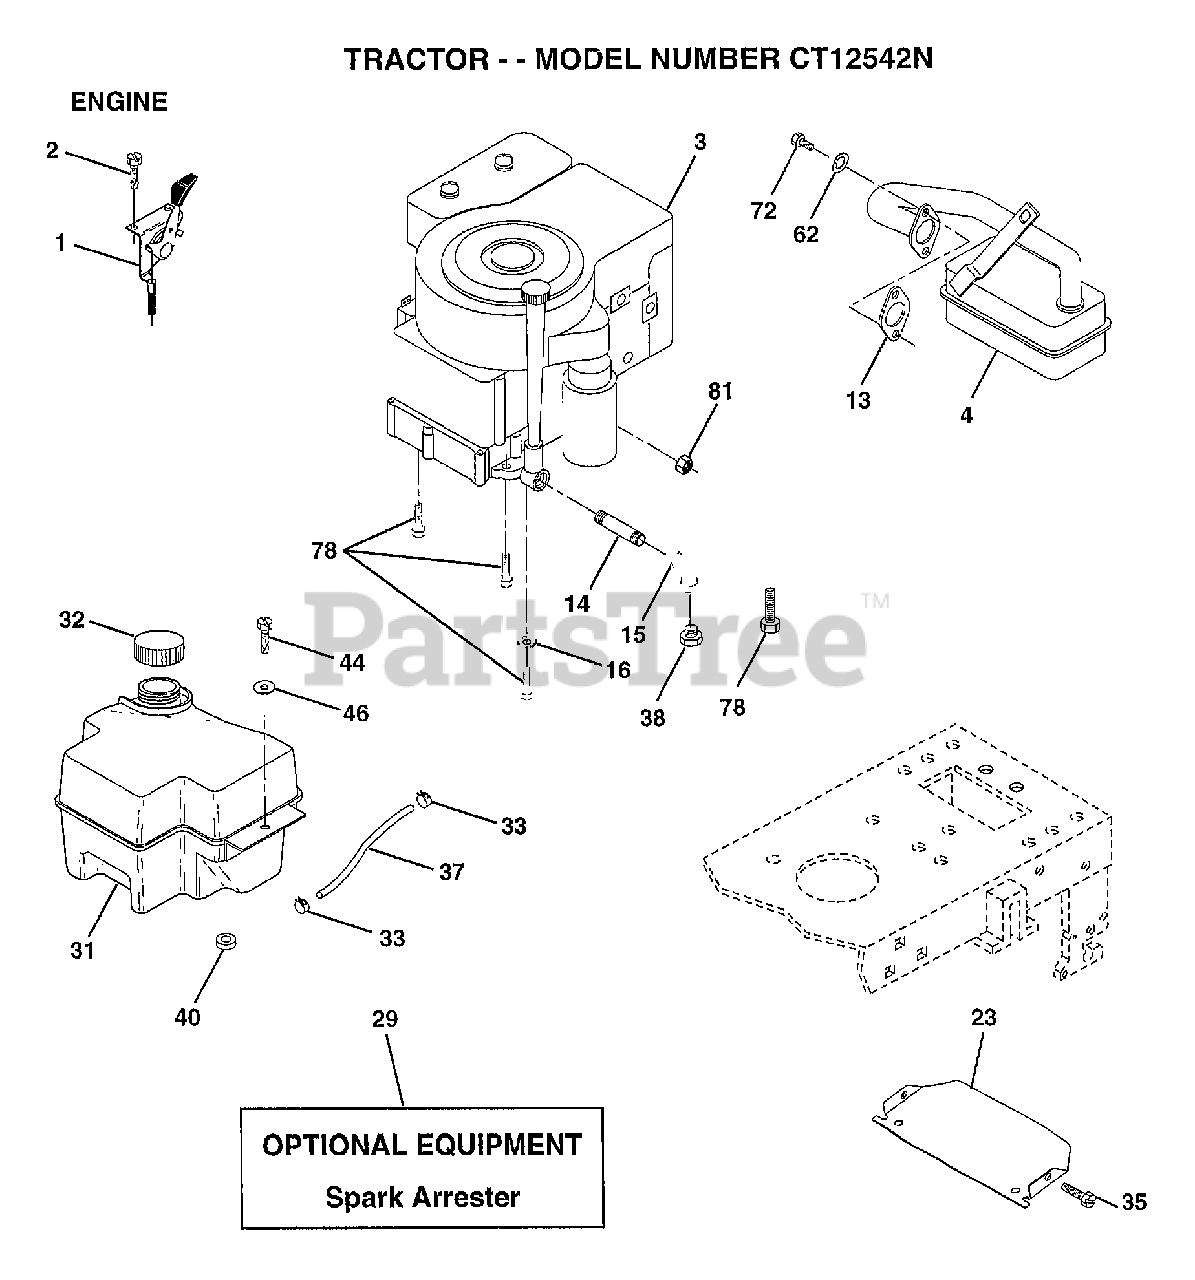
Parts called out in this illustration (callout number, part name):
1	CONTROL THROTTLE
2	SCREW LT
4	MUFFLER
13	GASKET ENG 1 313 LD TIN PLATED
14	PIPE NIPPLE
15	ELBOW
16	LOCKWASHER
23	SHIELD-HEAT
32	CAP ASM FUEL
33	HOSE CLAMP
35	SCREW
37	LINE FUEL
44	SCREW HEX CRT
46	WASHER
62	LOCKWASHER
72	SCREW
78	SCREW
81	NUT
